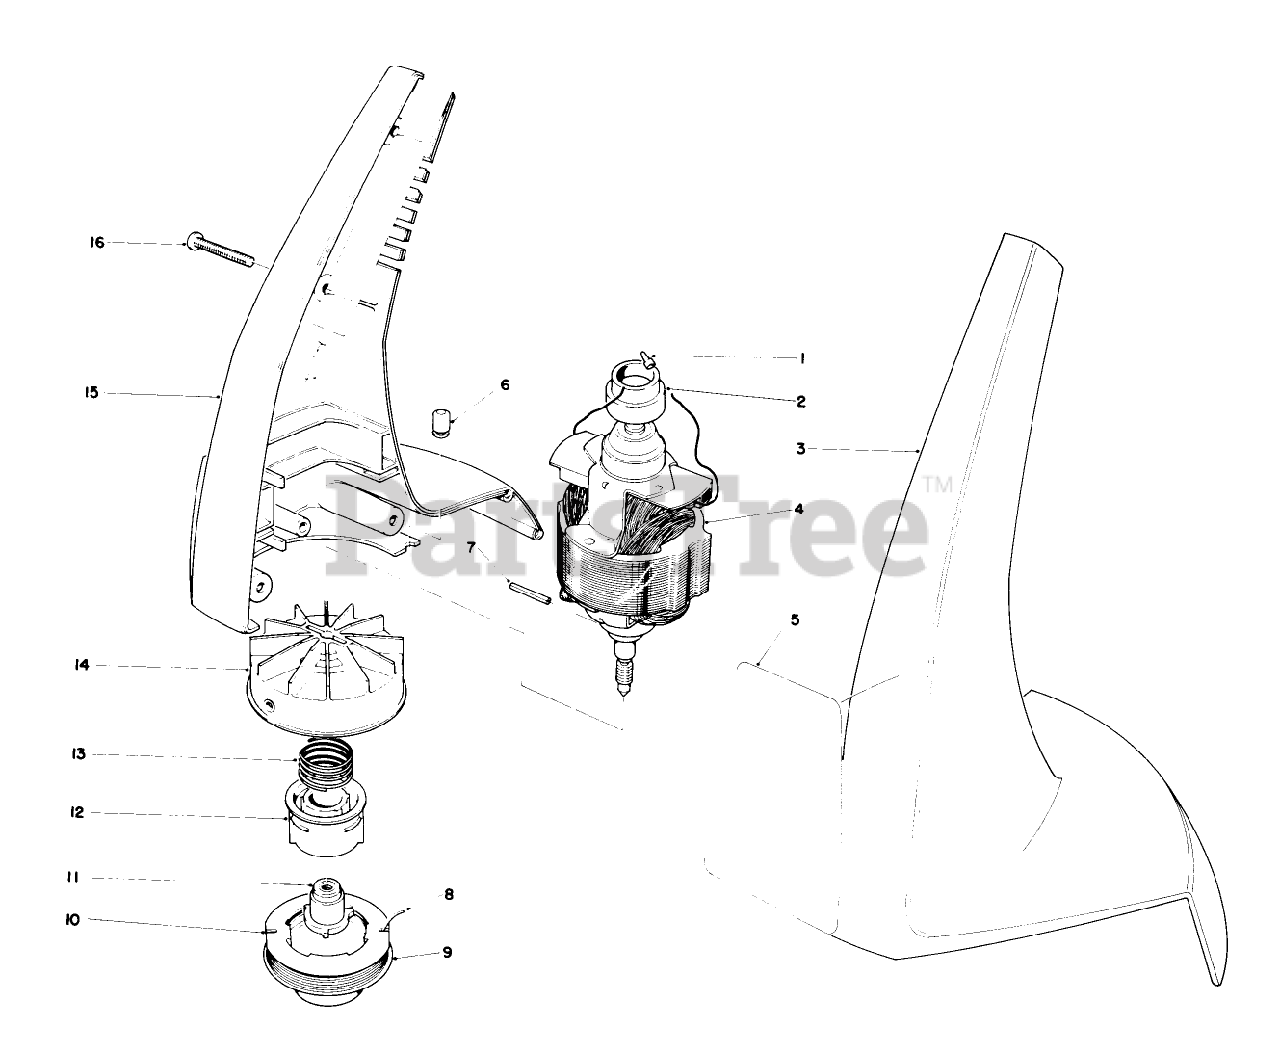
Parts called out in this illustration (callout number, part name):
1	CONNECTOR WIRE JOINT
2	Adapter-Motor
3	LH HOUSING
4	Motor
5	Decal-900
6	GROMMET
7	COIL PIN
8	.040" Cutting Line in Coil
9	SPOOL CAP
10	Prewound Spool
11	Driver
12	CORE - SPOOL
13	SPRING-COMPRESSION
14	FAN HUB ASM
15	RH HOUSING ASM
16	Screw
